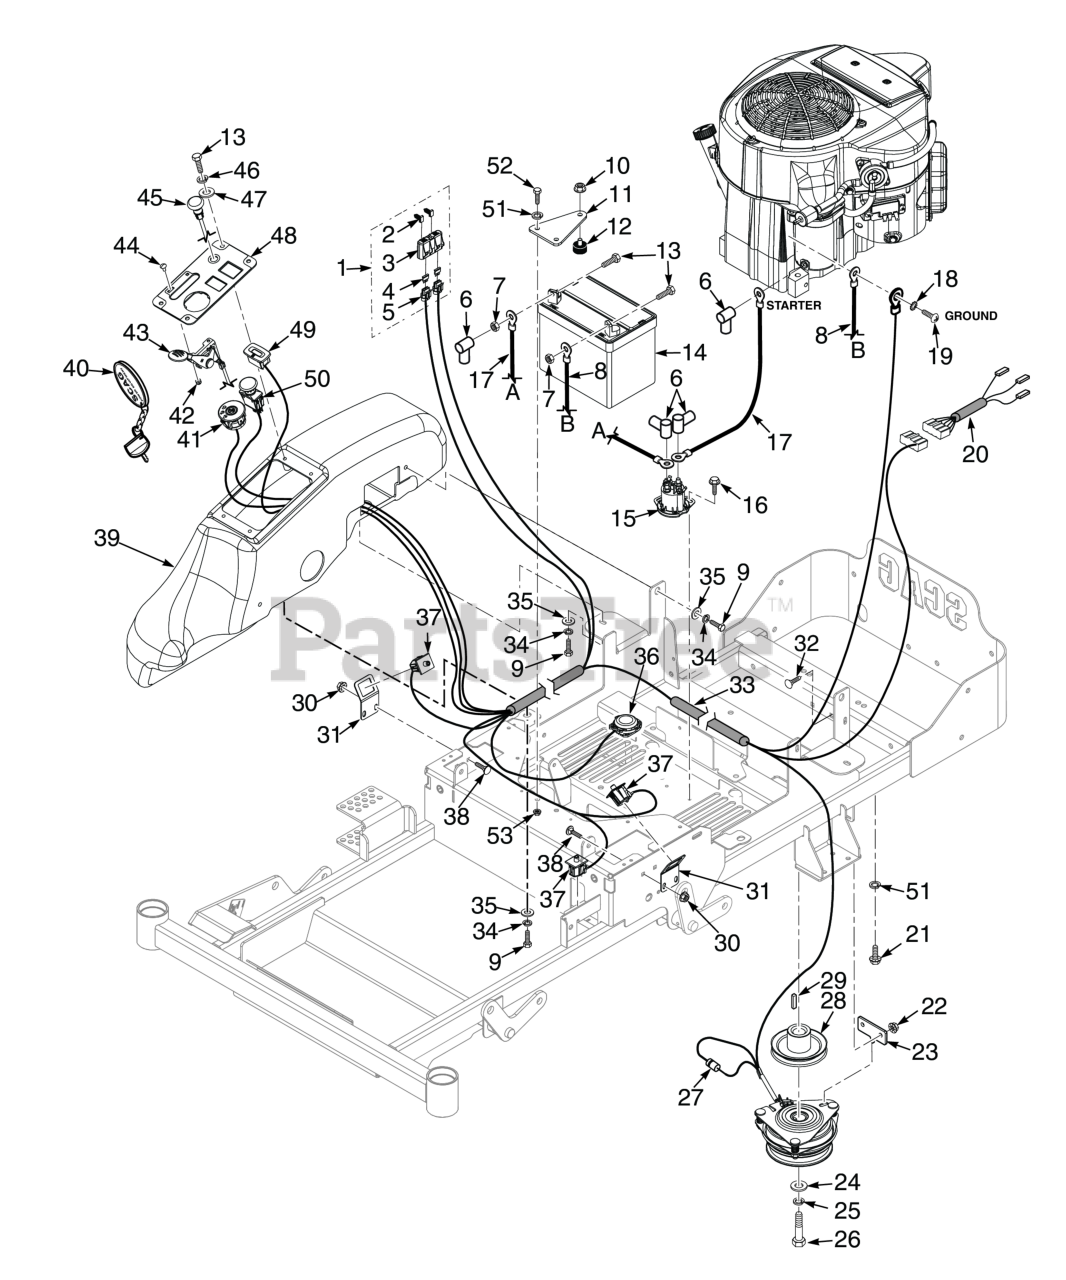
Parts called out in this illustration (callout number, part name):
1	Double Fuse Assy.
2	Clip, Fuse Holder
3	Cover, Sealed Double
4	FUSE, 20 AMP BLADE TYPE AUTOMOTIVE
5	Fuse Holder Assembly
6	RUBBER BOOT
7	Nut, 1/4 - 20 Hex
8	Battery Cable, 31-1/2" Black (25KA, 26DFI, 31DFI) - Kawasaki
9	BOLT, SERRATED FLANGE HEX HEAD 5/16-18 X 3/4"
10	Nut, Serrated Flange 5/16-18 (Right Front Engine Mounting, Briggs and Kohler Only)
11	Battery Hold Down
12	Bumper, Rubber 5/16-18 x 5/8"
13	Bolt, Hex Head 1/4-20 x .5" Battery, (Not Available Through Scag)
14	Battery, 12v - 230CCA
15	Solenoid, Sealed (Briggs & Stratton)
16	Screw, Self-Tapping 1/4-20 x 3/4
17	Battery Cable, 18" Red w/Braid (25KA, 26DFI, 31DFI) - Kawasaki
18	Lockwasher, 5/16" Ext. Tooth (Kohler x1)
19	Bolt, Hex Head M8 - 1.25 x 16 (48V / 52V)
21	Bolt, Hex Head 3/8-16 x 1-1/4", Kawasaki FX / FT & FT-EFI
22	Nut, Flange Head Elastic Stop 5/16-18
23	Plate, Anti-Rotation
24	Flatwasher, 7/16-.469 x 1.75 x .25 (48, 52)
25	Lockwasher, 7/16� Spring
26	Bolt, Hex Head 7/16-20 x 3¼" w/Patch
27	Diode, 600V 6 Amp
28	Pulley, 4-1/2" - 1" Bore
29	Key, 1/4 x 1/4 x 1.25" Pulley Mtg.
30	Nut, Flanged Elastic Stop 1/4-20
31	Bracket, Switch
32	Bolt, 5/16-18 x .75 RHSN Carriage
33	Wire Harness
34	Lockwasher, 5/16 (.317 x .586 x .078) Helical Spring
35	Flatwasher, 5/16-.375 x .875 x .083 (35BV & 37BV-EFI)
36	Switch, Double Pole - Twist
37	Switch, Double Pole - Plunger
38	Serr. Fl. Hex Head CPSCR, 1/4-20 x 3/4"
39	Console Tank w/Decals, SZL-36
40	Key, Assembly w/Fob
41	Ignition Switch
42	Nut, Elastic Stop #10-24
43	Throttle Control, Kawasaki
44	Bolt, Carriage #10-24 x 1/2"
45	Choke Control, Kawasaki
46	Lockwasher, 1/4� Spring
47	Flatwasher, 1/4" (.312 x .750 x .065")
48	Instrument Panel w/Decal, SZL-36
49	Hour Meter, Inductive
50	Switch, PTO - 10 Amp
51	Lockwasher, 3/8" Spring, Kawasaki FX / FT & FT-EFI / B&S 32BV
52	Bolt, Hex Head, 3/8-16 x 1 Gr. 5
53	Threaded insert, Hex Head (Pressed)
